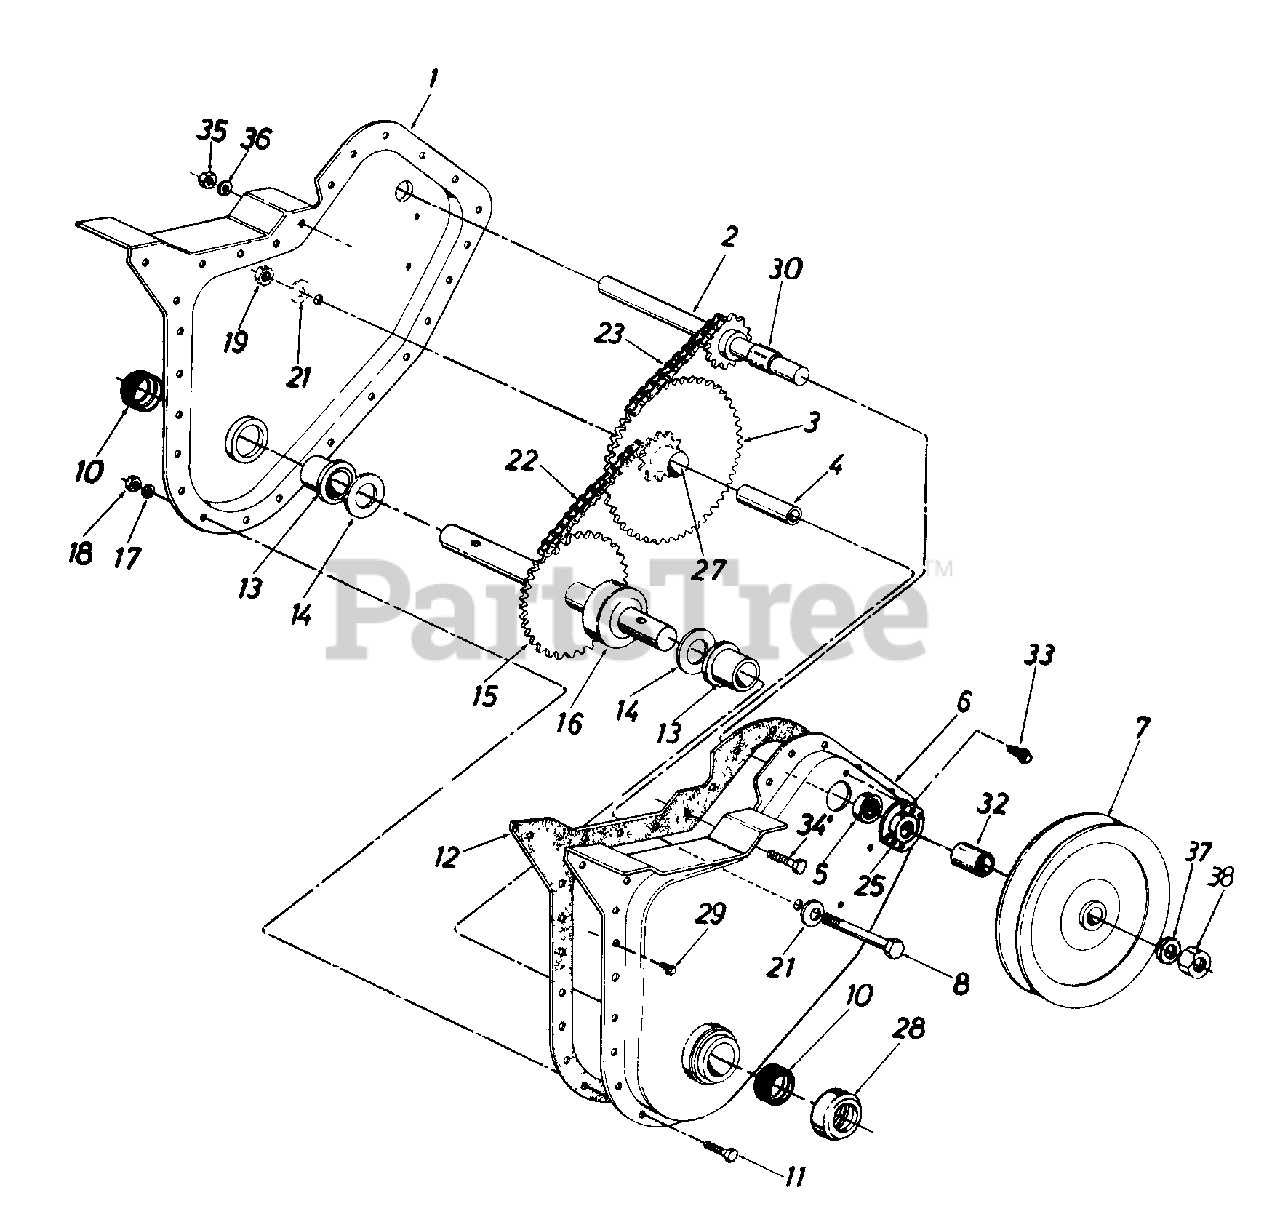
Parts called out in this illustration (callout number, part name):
3	Hub and Sprocket Ass'y.
4	Bearing Inner Race
5	Ball Bearing
8	Hex Bolt 3/8-24 x 2.5"
10	Seal
11	Hex Bolt 1/4-28 x .625"
12	Gasket
13	Flange Brg..879" I.D.
14	Fl-Wash. .88" I.D. x 1.5"
15	Tine Shaft Ass'y.
16	Spacer 7/8" I.D.
17	L-Wash. 1/4" I.D.
18	Hex Nut 1/4-28 Thd.
19	Hex Ins. L-Nut 3/8-24 Thd.
21	Bell-Wash. .406" I.D.
22	Chain #420 1/2" Pitch 38 Links
23	Chain #35 .375" Pitch 50 Links
25	Bearing Housing
27	Bearing
28	Dust Cap
29	Hex Wash. Hd. Self-Tap Scr. 1/4-20 x .50" Lg.
30	Spacer.63" I.D. x .77" O.D. x .38" Lg.
32	Spacer .647 x .77"
33	Hex Wash. Hd. Self-Tap, Scr. 1/4-20 x .38" Lg.
34	Hex Bolt 5/16-18 x .75" Lg.
35	Hex Nut 5/16-18 Thd.
36	L-Wash. 5/16" I.D.
37	Bell-Wash. .38" I.D. x .88" O.D.
38	Hex Flange L-Nut 3/8-24 Thd.
